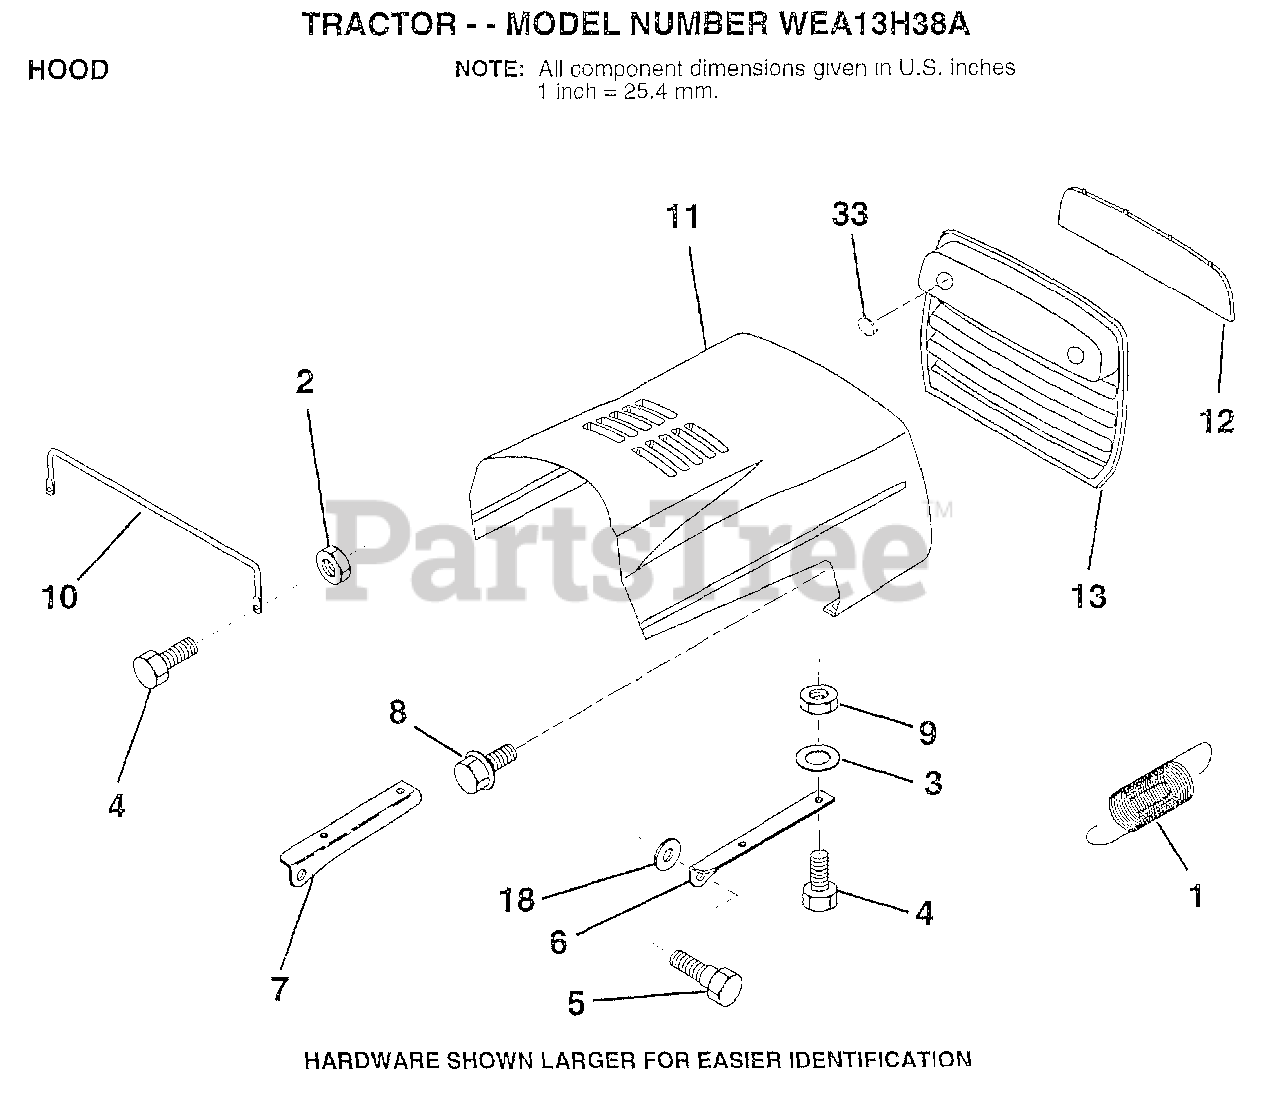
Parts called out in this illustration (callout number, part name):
1	EXT SPRING
2	NUT
3	WASHER
5	BOLT.SHLD.5/16-18
6	BRKT HOOD RH
7	BRKT HOOD LH
8	SCREW SLTD HXHD
9	NUT
10	"BRACE,HOOD"
11	HOOD.IMPREG.MS550
12	LENS
13	GRILL
18	WASHER
